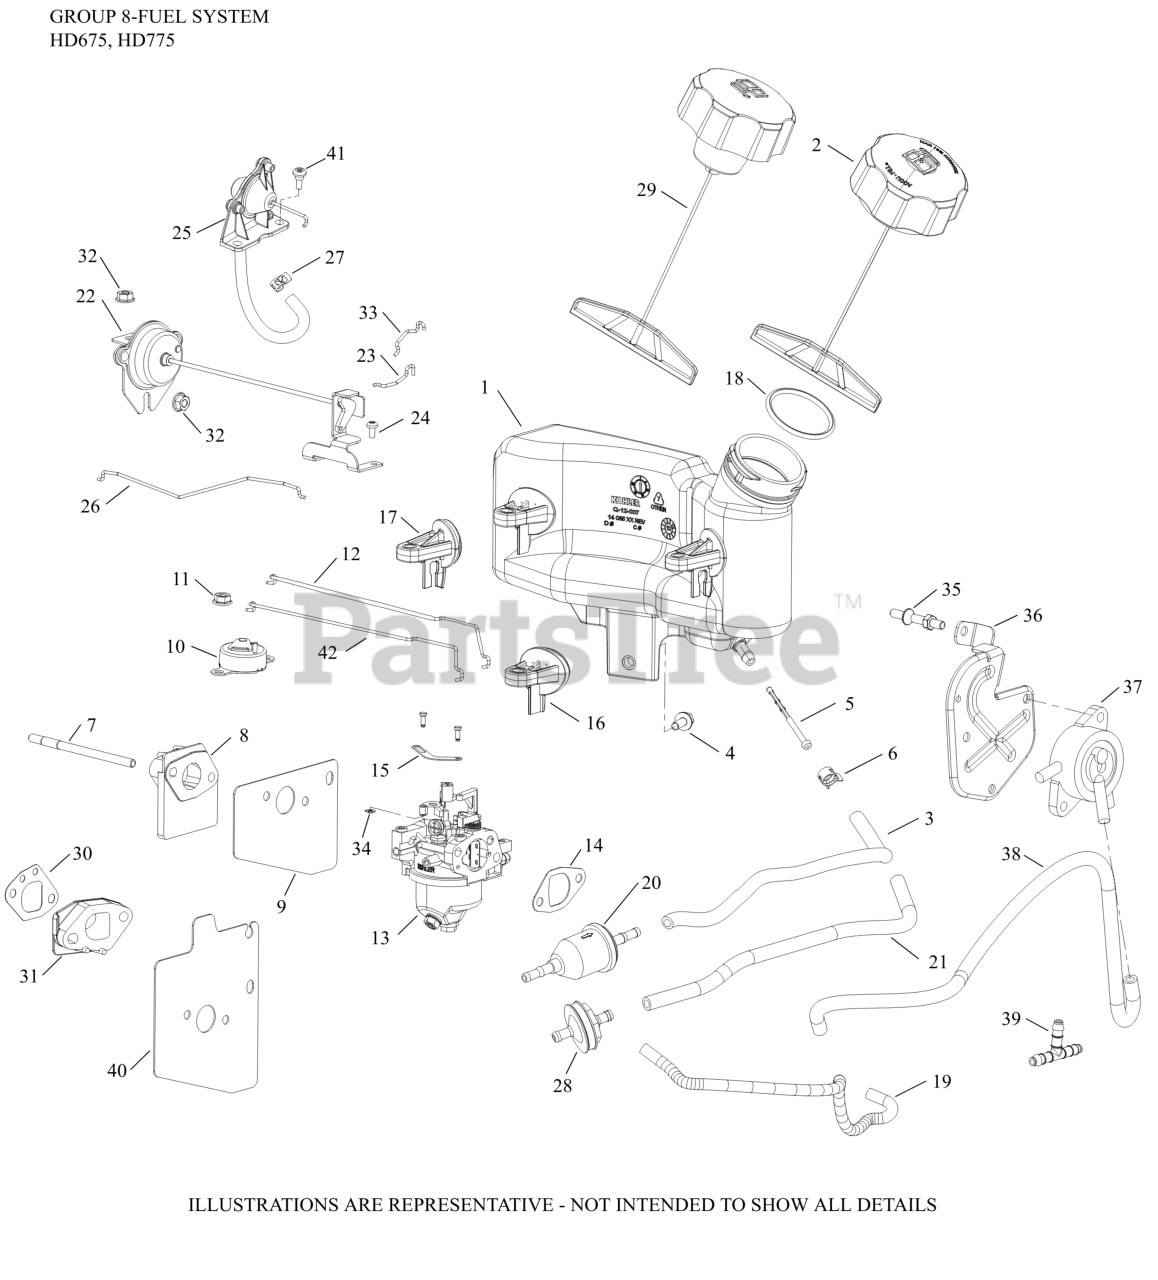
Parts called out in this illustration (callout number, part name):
1	TANK, FUEL
2	FUEL CAP ASSEMBLY
3	HOSE, FUEL LOW-PERMEATION
4	SCREW, THREAD FORMING-USE 25 086 472-S
5	FILTER, FUEL IN-NIPPLE
6	CLAMP, HOSE
7	STUD,M6X1.0X100.2MM
8	KIT, SPACER
9	KIT, CARBURETOR HEAT SHIELD GASKET
13	KIT, CARBURETOR 13 MM AUTO CHOKE
14	KIT, INTAKE GASKET
16	BRACKET, FUEL TANK
17	BRACKET, FUEL TANK
22	ARM ASSEMBLY, AUTO CHOKE
23	LINKAGE AUTO CHOKE
24	SCREW, M4 THREAD FORMING
25	DIAPHRAGM, ASSEMBLY
26	LINKAGE, CHOKE
27	CLAMP, HOSE
32	NUT, HEX FLANGE (M6)
41	SCREW, SHOULDER
NI	KIT, HIGH ALTITUDE - USE 14 755 04-S
NI	KIT, HIGH ALTITUDE (ABOVE 8,000 FT.)
NI	KIT, CARBURETOR REPAIR (RUIXING)
